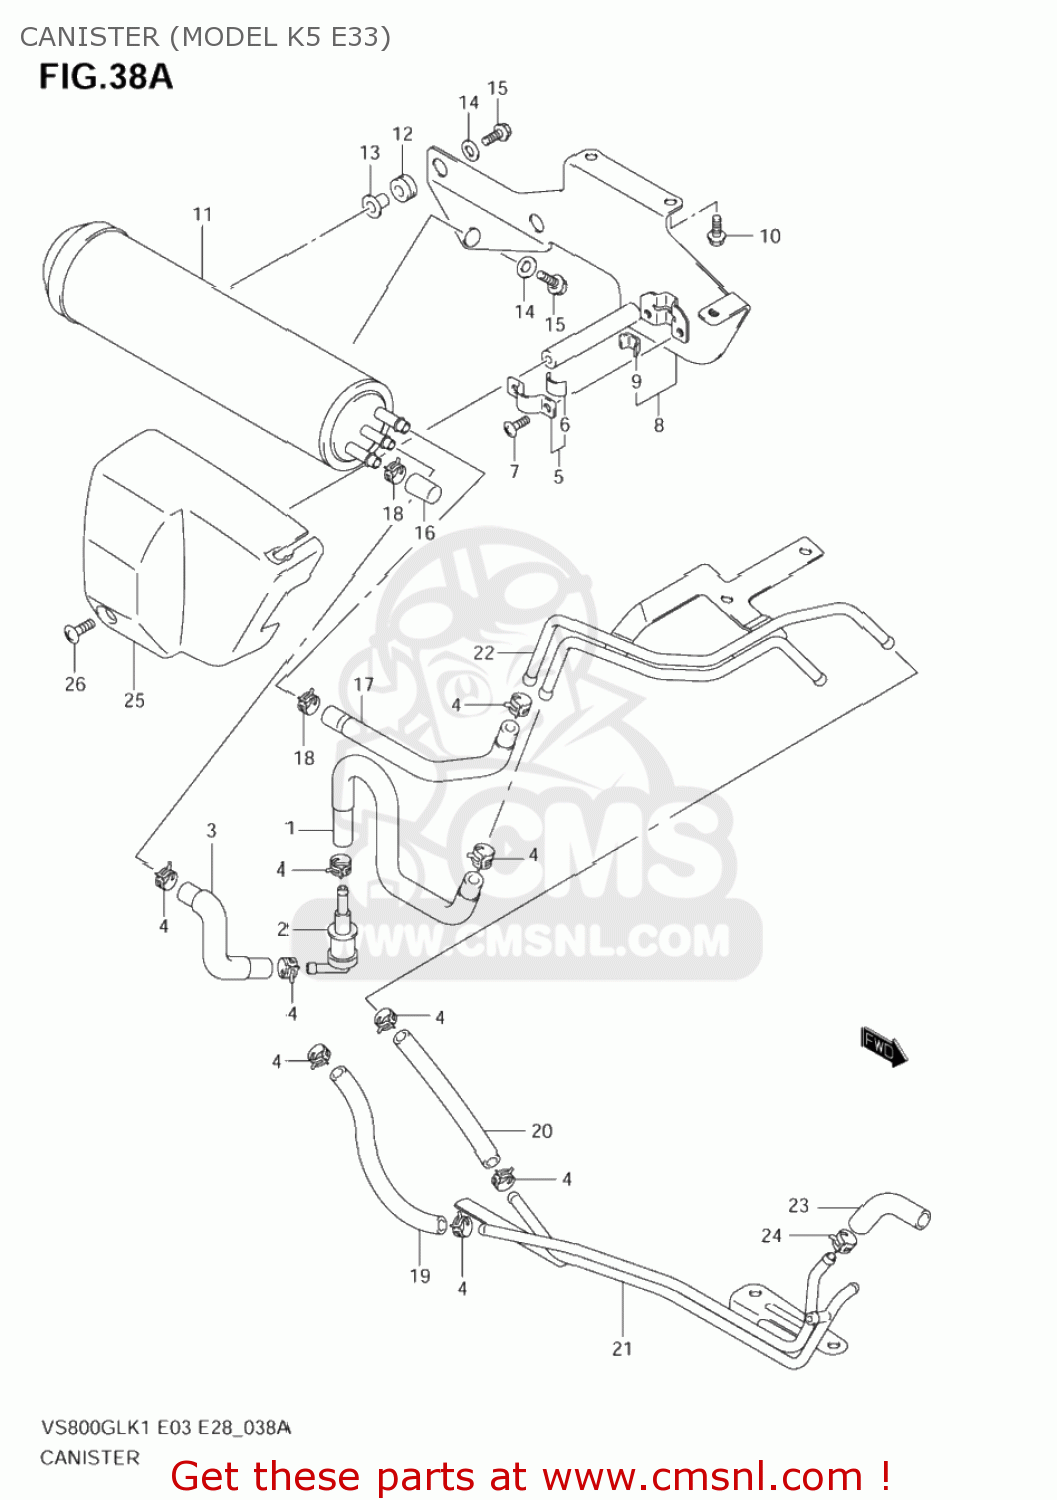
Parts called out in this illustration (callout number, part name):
1	HOSE,TANK & BREATHER VALVE
2	VALVE,FUEL TANK BREATHER
3	HOSE,CSTR & BREATHER VALVE
4	CLIP
5	PLATE,FUEL TANK BREATHER NO.2
6	CUSHION
7	SCREW
8	BRACKET,CANISTER
9	CUSHION
10	BOLT
11	CANISTER SET
12	CUSHION
13	WASHER
14	WASHER(6.5X16X3.2)
15	BOLT
16	CAP,OD:11.5
17	HOSE,CSTR PURGE
18	CLIP
19	HOSE,EVAP SYSTEM SURGE
20	HOSE,EVAP SYSTEM PURGE
21	PIPE,CSTR JOINT FR
22	PIPE,CSTR JOINT RR
23	HOSE(5.4X11.4X600)
24	CLIP
25	COVER,BREATHER VALVE
26	SCREW(5X13)
